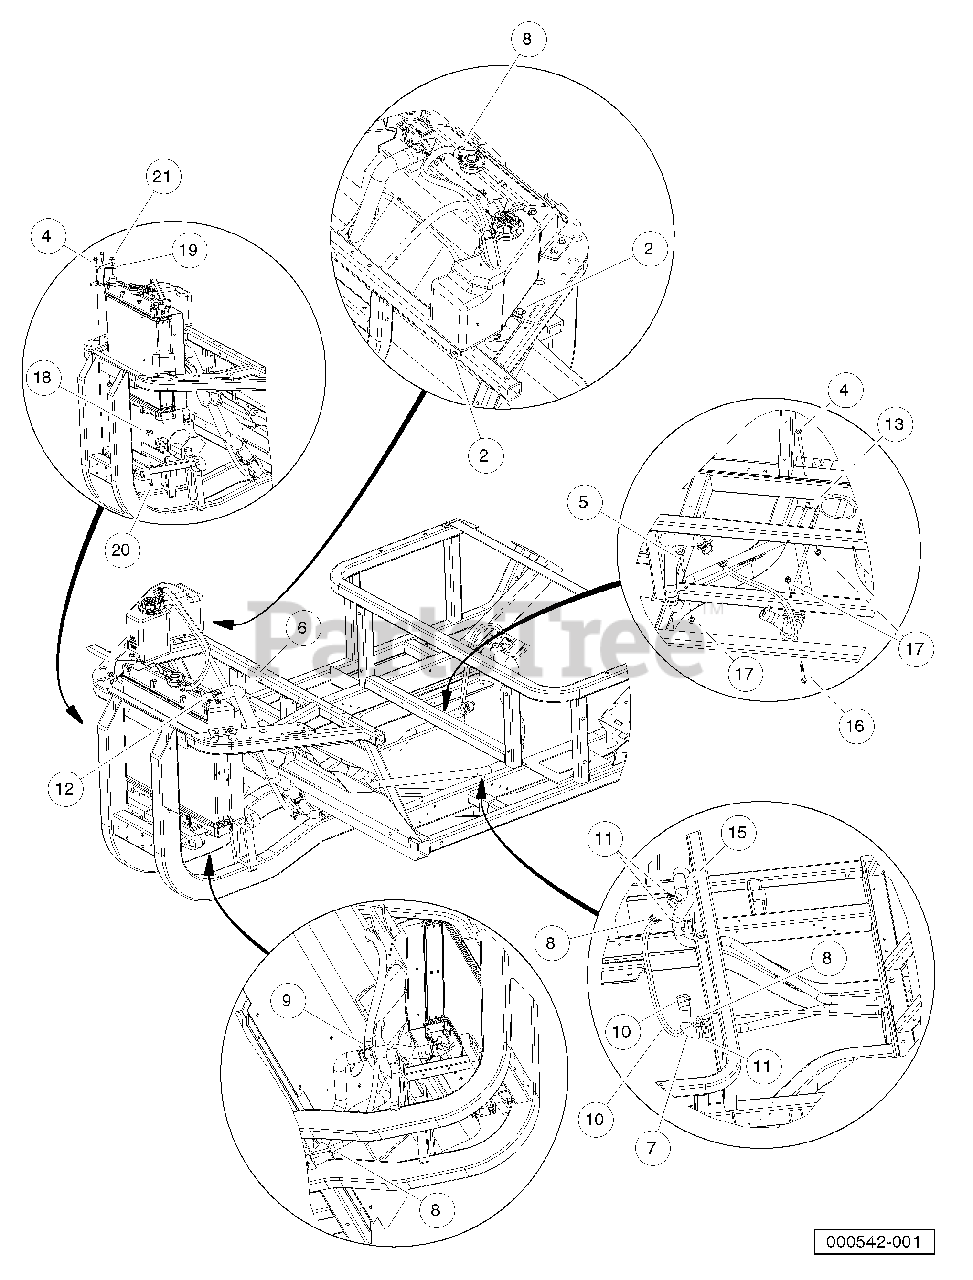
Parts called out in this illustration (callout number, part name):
1	Instl, Cooling Sys, Diesel
2	Screw, 5/16-18 X 0.75 Thread-Forming
3	Bolt-hex Fl, M8 X 1.25 X 135
4	Screw, M8X1.25X30, Hex
5	M8-1.25 X 80 Sems
6	Hose, Coolant Upper Rad
7	Hose, Coolant Lower Eng
8	Clamp, Hose, CTB 15mm
9	Clamp, Hose, CTB 22mm
10	Clamp, Hose, Ctb 30mm
11	Clamp, Hose, Ctb 35mm
12	Clamp, Hose, Ctb 38mm
13	Clamp, Bar
14	Hose, Vent Tube To Eng, Coolnt
15	Hose, Coolant, Return, Engine
16	Bolt Flanged Head, M8 X 1.25 X 65
17	Lock Nut, Flg M8 X 1.25 Nylon
18	Bumper, 19mm Stud
19	Bracket, Radiator Support
20	Nut Flg, M6 X 1 Serrated
21	Nut Flg, M8 X 1.25 Serrated
